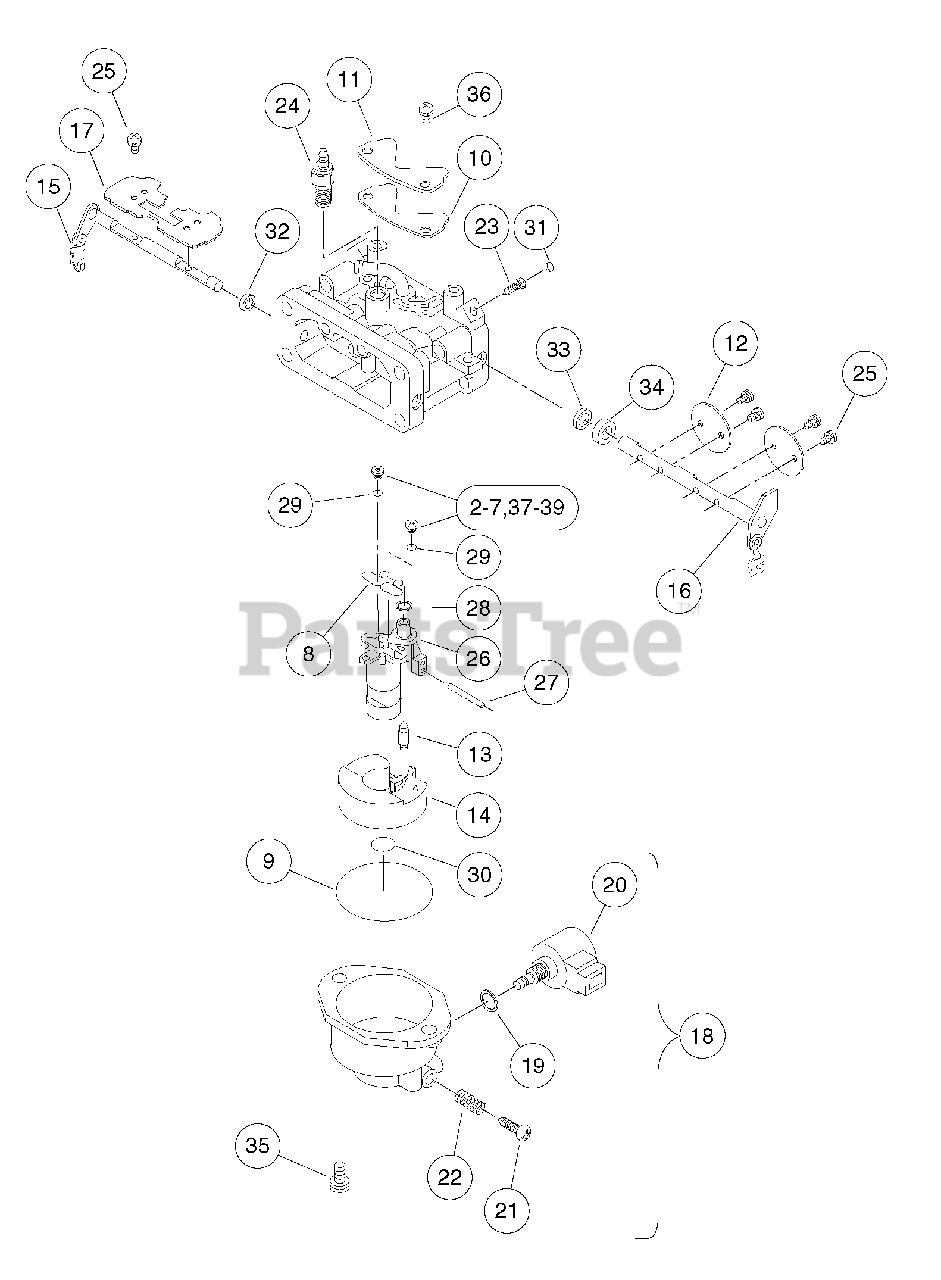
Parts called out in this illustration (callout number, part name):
1	Asm, Carburetor, FH680D
2	Kit, Jet, 6600 Ft +, Fh680d
3	Jet, Push In #96, FH680D (6600 ft and higher (2000 m and higher))
4	Kit, Instructions Jet, Push In
5	Kit, Jet, 3300-6600 Ft, Fh680d
6	Jet, Push In #99, FH680D (3300-6600 ft (1000-2000 m))
7	Kit, Instructions Jet, Push In
8	Gasket, Fh680d
9	Gasket, Carburetor, Dia. 52
10	Gasket, Cover, Fh680d
11	Cover, Slow Passage, Fh680d
12	Valve, Throttle, Fh680d
13	Valve, Float, Fh680d
14	Float, Carburetor, Fh680d
15	Shaft, Carburetor, Fh680d
16	Shaft, Carburetor, Throttle
17	Valve, Carburetor, Fh680d
18	Asm, Chamber, Float, Fh680d
19	Gasket, Carburetor, Fh680d
20	Solenoid, Carburetor, Fh680d
21	Screw, Drain, Carburetor
22	Spring, Carburetor, Fh680d
23	Needle, Jet, Fh680d
24	Heater, Carburetor, Fh680d
25	Screw, Carburetor, M3 X 6
26	Spacer, Carburetor, Fh680d
27	Pin, Carburetor, Fh680d
28	O-ring, Carburetor, Dia. 6.5
29	O-ring, Carburetor, Fh680d
30	O-ring, Carburetor, Dia. 9
31	Plug, Expansion, Carburetor
32	Seal, Carburetor, Dia. 5.9
33	Seal, Carburetor, Fh680d
34	Collar, Carburetor, Fh680d
35	Screw, Carburetor, M5
36	Screw, Carburetor, M4
37	Kit, Jet, 0-3300 ft. FH680D
38	Jet, Push In #102, FH680D (0-3300 ft (0-1000 m))
39	Jet, FH680D
